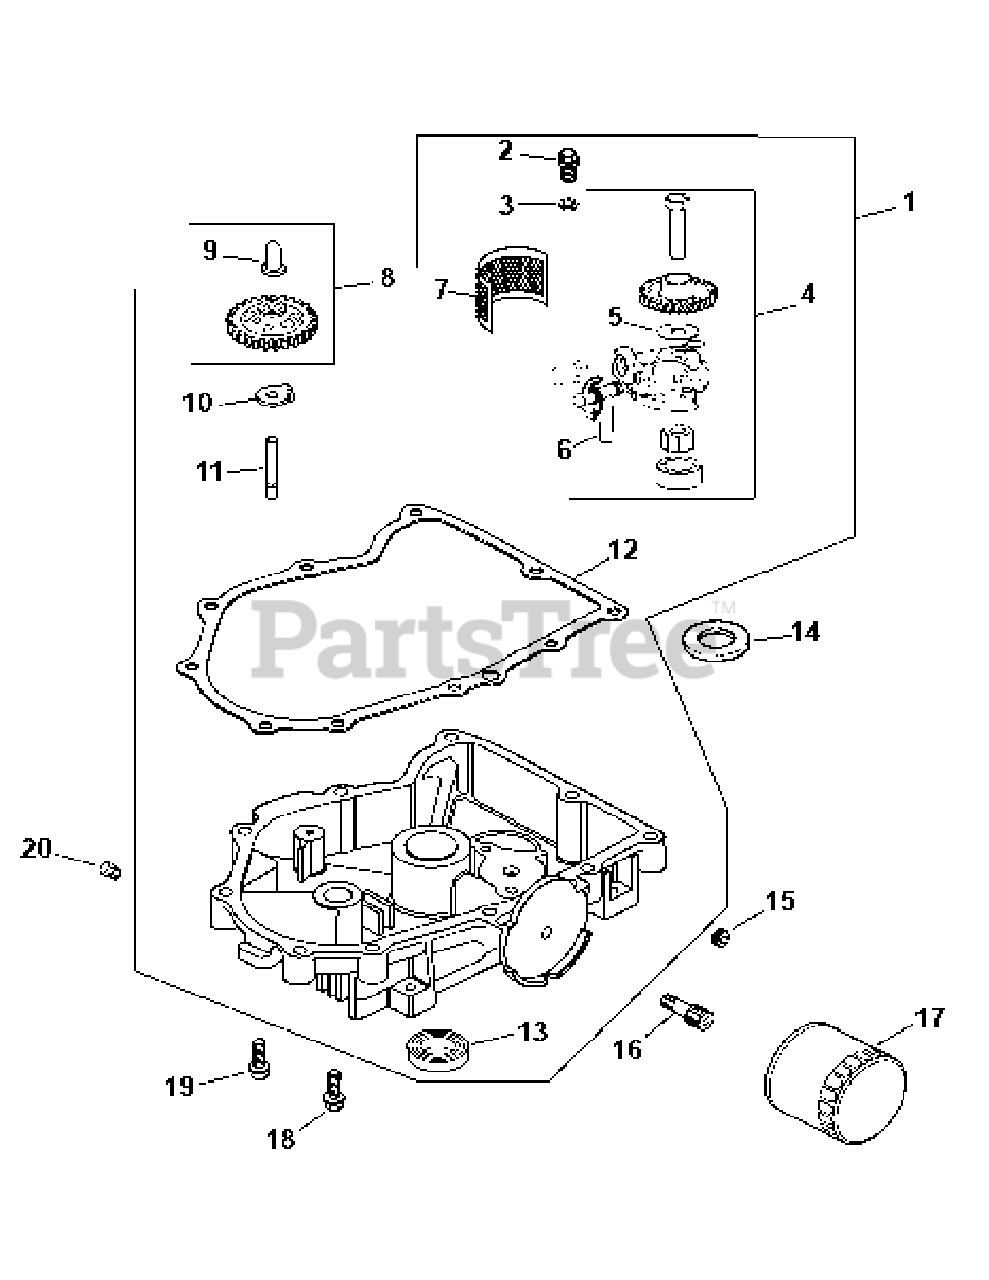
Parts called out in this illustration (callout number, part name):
1	Oil Pan w/Gasket Kit
2	Screw
3	FLAT WASHER
4	Oil Pump Kit
6	Oil Pickup Tube
8	Governor Gear w/Pin Kit
11	Governor Gear Shaft
12	Oil Pan Gasket
13	Seal
16	Oil Filter Nipple
17	Oil Filter
18	Hex Flange Screw
19	Hex Flange Screw (M6 x 1.0 x 25)
